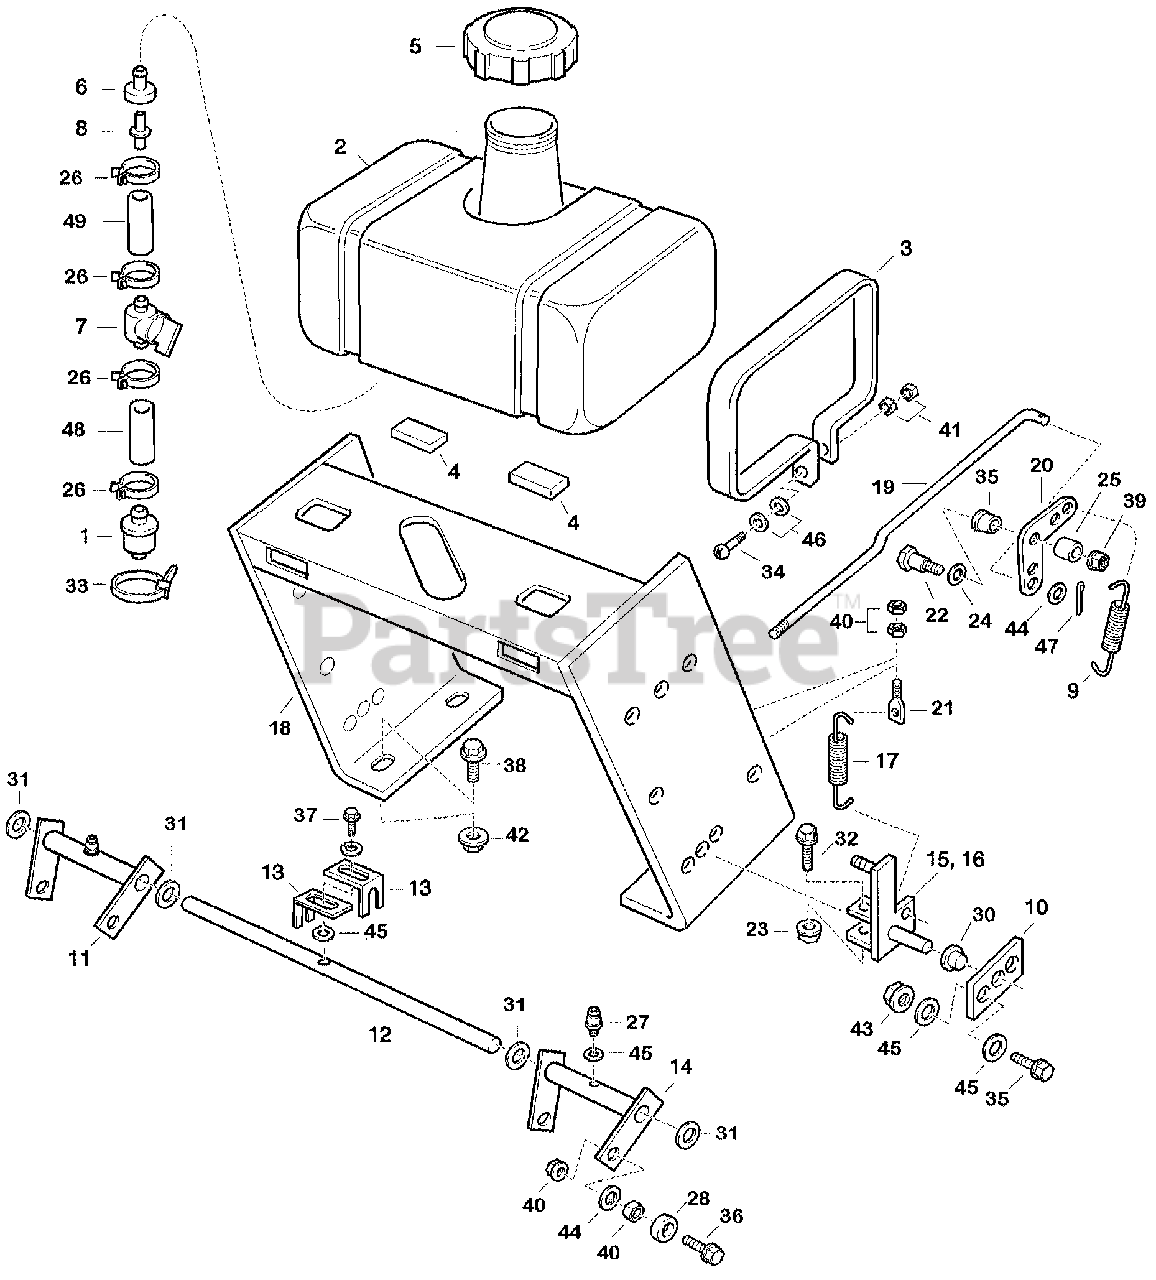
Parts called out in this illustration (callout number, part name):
1	FILTER, FUEL
2	TANK, FUEL (4.2)
3	STRAP, FUEL TANK
4	PAD, FUEL TANK
5	CAP, FUEL TANK
6	JOINT, CONNECTOR FUEL
7	VALVE, FUEL SHUT-OFF
8	PIPE, FUEL
9	SPRING, TENSIONER
10	SUPPORT, PUMP SHAFT
11	ARM, R. SPEED STOP
12	SHAFT, CROSS
13	SPACER, CROSS SHAFT
14	ARM, L. SPEED STOP
15	ARM, R. PUMP
16	ARM, L. PUMP
17	SPRING, PUMP ARM
18	SUPPORT, HANDLE
19	ROD B, P.T.O.
20	BELLCRANK (3")
21	BOLT, SPRING ADJUSTER
22	BOLT, SHOULDER (3/8"-16)
23	NUT, SELF-LOCK (5MM)
24	WASHER, BELLEVILLE (1/2")
25	SPACER (1/2")
26	CLAMP, FUEL LINE
27	NIPPLE, GREASE
28	BEARING, PUMP STOP
29	BUSHING, SNAP
30	BUSHING, PUMP ARM
31	BUSHING (5/8")
32	BOLT, HEX. (5X25)
